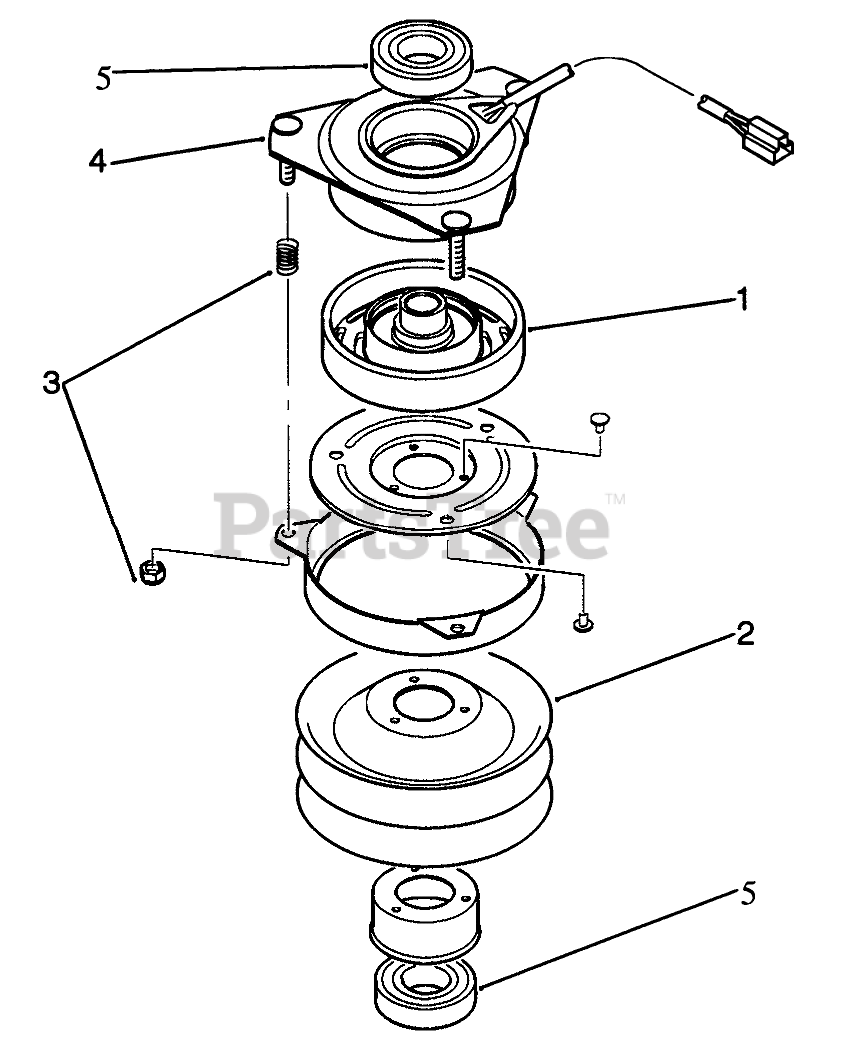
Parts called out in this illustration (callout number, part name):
1	Assembly-Rotor
2	Assembly-Armature
3	Accessories-Nuts & Springs
4	Assembly-Field
